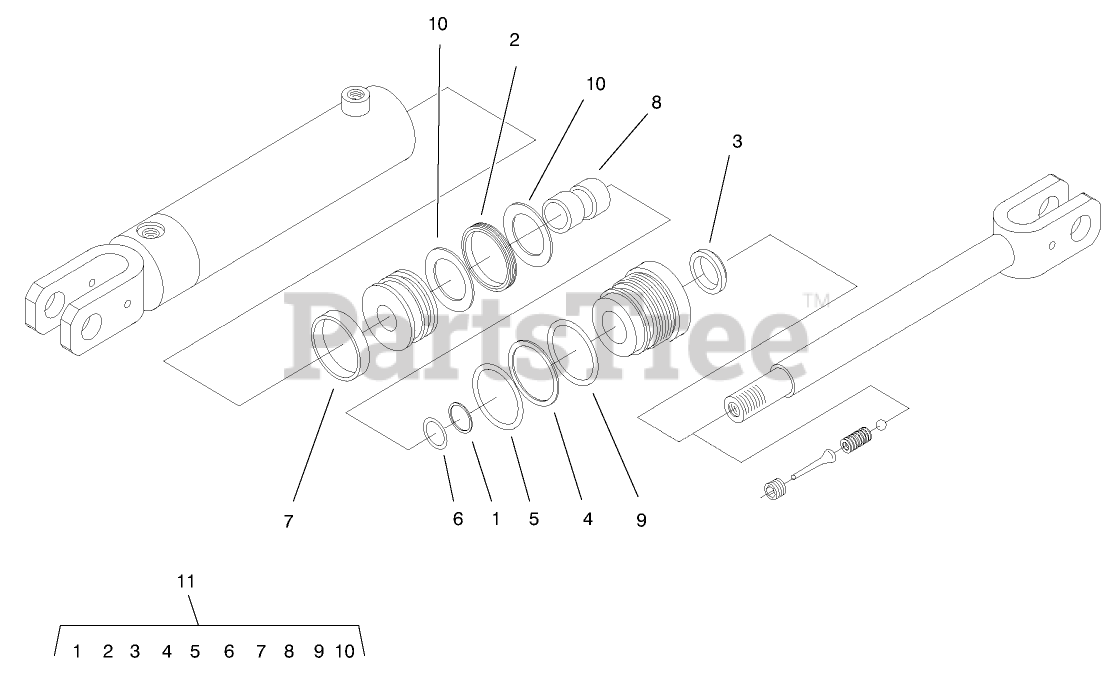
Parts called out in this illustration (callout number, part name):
2	PSP Seal
3	Rod-Wiper
6	Polypak
7	Ring-WEAR
8	Ring-WEAR
